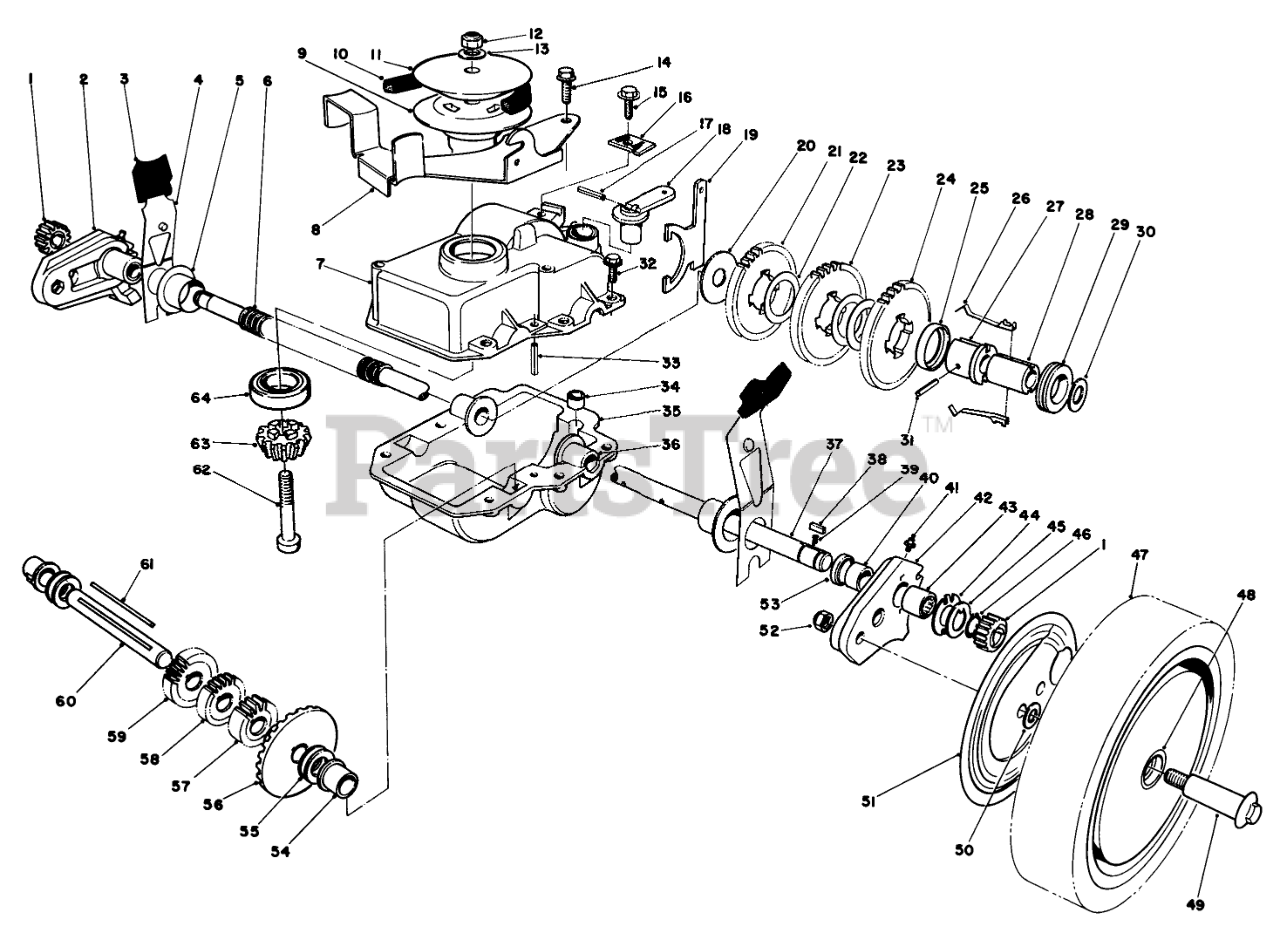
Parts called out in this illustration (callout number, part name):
1	GEAR-PINION
2	Pivot Arm Assembly-R.H. (Incl. Ref. #40, 41, 43 & 53)
3	KNOB-ARM
4	SPRING ARM ASM SP
5	CAP-END
6	CONDUIT-CONVOLUTED, SPLIT
7	Case-Upper
8	BELT GUIDE BRKTB
9	PULLEY-LOWER HALF
10	V-BELT
11	PULLEY-UPPER HALF
12	NUT-LOCK, NI
13	WASHER-FLAT
14	SCREW
15	SCREW-HWHTF
16	Cable Clamp
17	PIN-COIL
18	LEVER-SHIFT
19	Shift Yoke
20	WASHER
21	GEAR-38T
22	WASHER
23	GEAR-42T
25	RETAINER-KEY
26	KEY-SHIFT
27	SLEEVE-GEAR
28	SLEEVE
29	COLLAR-SHIFT
30	Washer
31	PIN-SPRING
32	SCREW-HWHTF
33	ROLL PIN 3/16 X 1 IN
34	BUSHING-YOKE
35	LOWER GEAR CASE CAST
36	Bushing-Output Shaft
37	Output Shaft
38	KEY RECTANGULAR
39	SPRING-COMPRESSION
40	BUSHING
41	FITTING-GREASE
42	Pivot Arm Assembly-L.H. (Incl. Ref. #40, 41, 43 & 53)
43	BEARING-ROLLER
44	INNER THRUST WASHER
45	WASHER-THRUST, OUTER
46	RING-RETAINING
47	Wheel, Tire & Gear Assembly (Incl. Ref. #48)
48	BUSHING
49	WHEEL BOLT
50	WASHER
51	WHEEL COVER
52	NUT-LOCK
53	SEAL-OIL
54	BUSHING
55	WASHER-THRUST
56	BEVEL GEAR
57	GEAR-12T
58	GEAR-14T
59	GEAR-18T
60	INTERMEDIATE SHAFT
61	Key Square
62	Screw-Socket Hd
63	BEVEL PINION
64	BEARING-BALL
